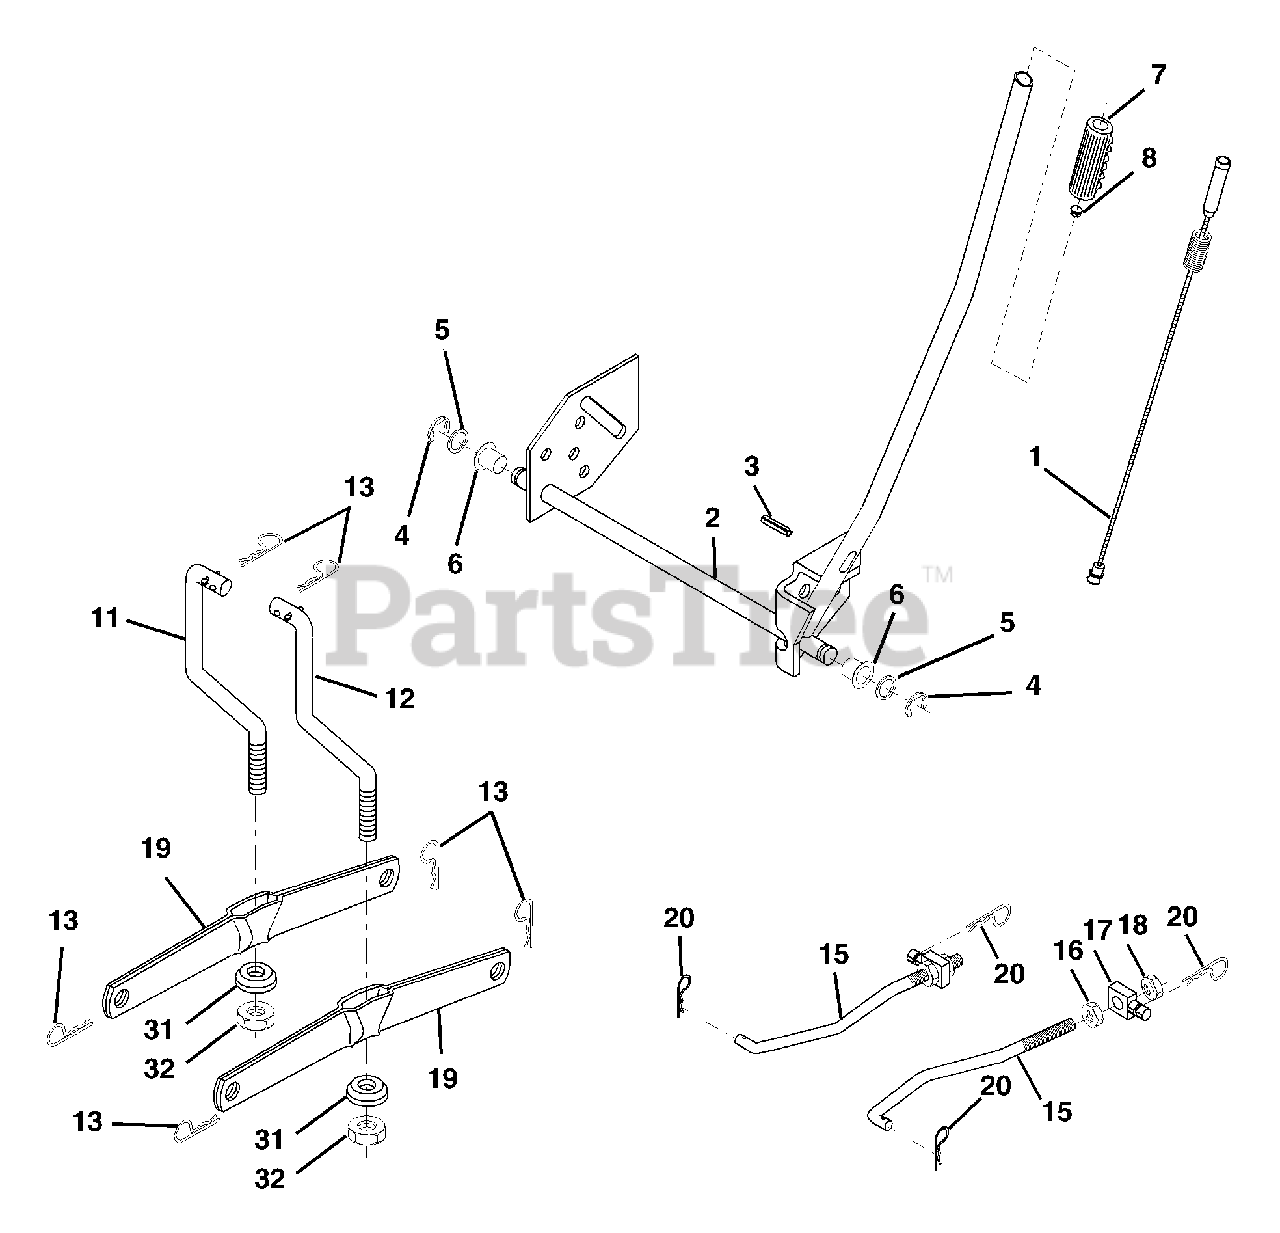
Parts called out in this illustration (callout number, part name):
1	Wire Asm Inner W/plunger
2	Shaft Asm Lift
3	Pin Groove 1 500 Zinc
4	E Ring #5133-62
5	Washer Pltd 21/32 X 1 X 21ga
6	Bearing Nylon Blk 629 Id
7	Grip Handle Fluted Blk
8	Button Plunger Red
11	Link Lift LH
12	Link Lift RH
13	Retainer Spring
15	Link Front
16	Nut Jam Hex 1/2-13 Unc
17	Trunnion Blk Zinc
18	Nut Lock w/Wsh 1/2-13 UNC
19	Arm Suspension Rear
20	Retainer Spring Zinc
31	Bearing Pvt Lift
32	Nut Crownlock 3/8-24
